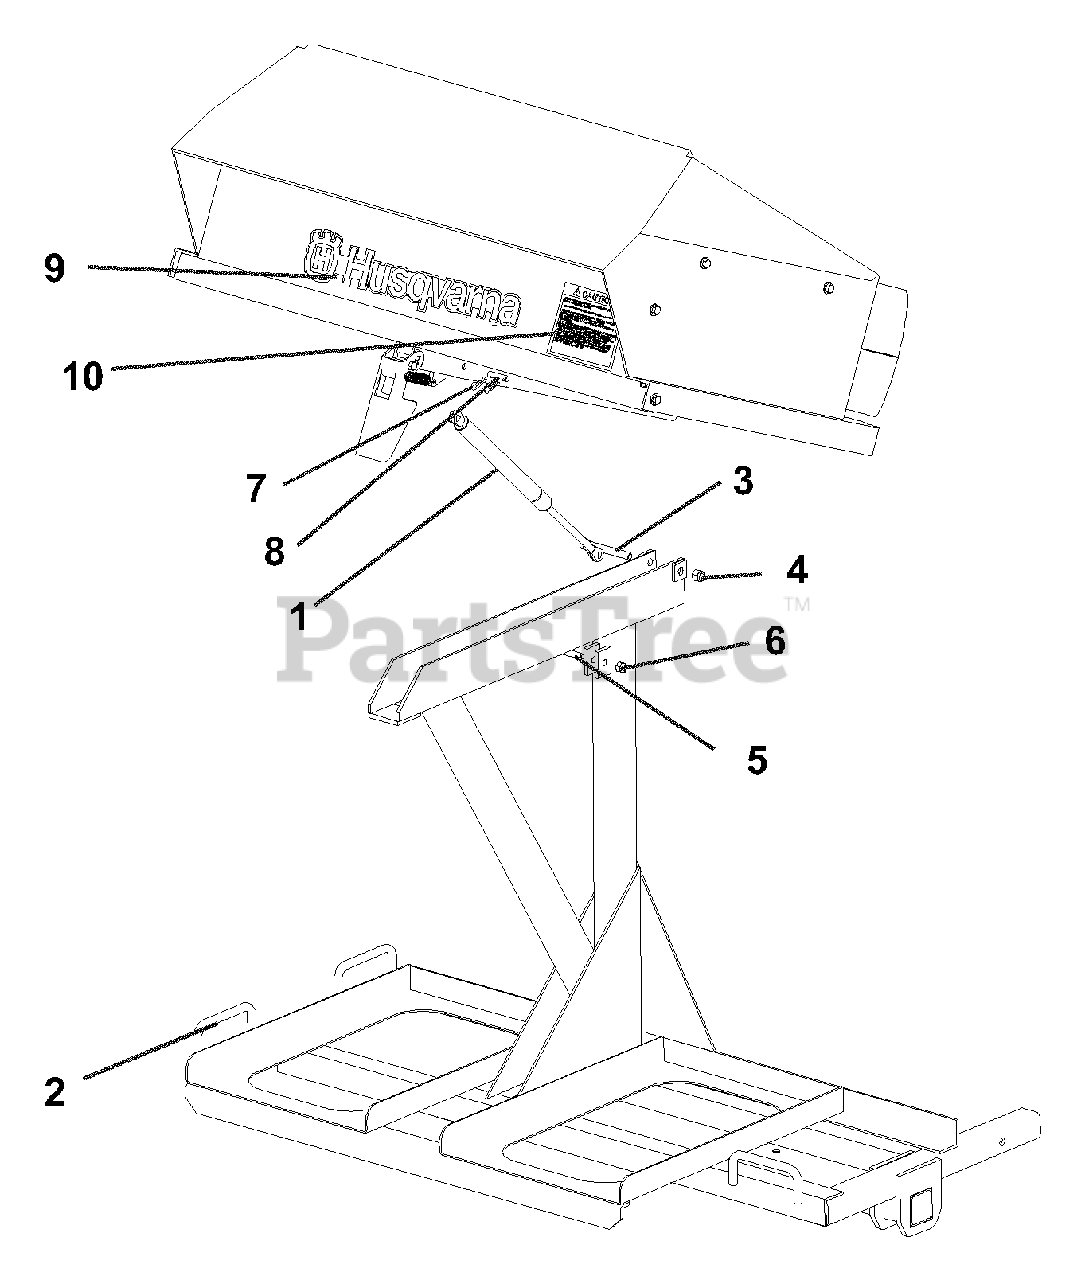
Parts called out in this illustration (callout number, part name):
1	Gas Spring
3	Bolt, Hex, 3/8"-16 x 3"
4	Nut, Hex, Nylon Lock, 3/8"-16
5	Bolt, Hex, 5/16"-18 x 1-1/2"
6	Nut, Hex, Nylon Lock, 5/16"-18
7	Pin, Cotter, #13
8	Pin, Clevis, 5/16" x 1-1/4" w/ 2 holes
9	Decal, Husqvarna
10	Decal, Caution List
